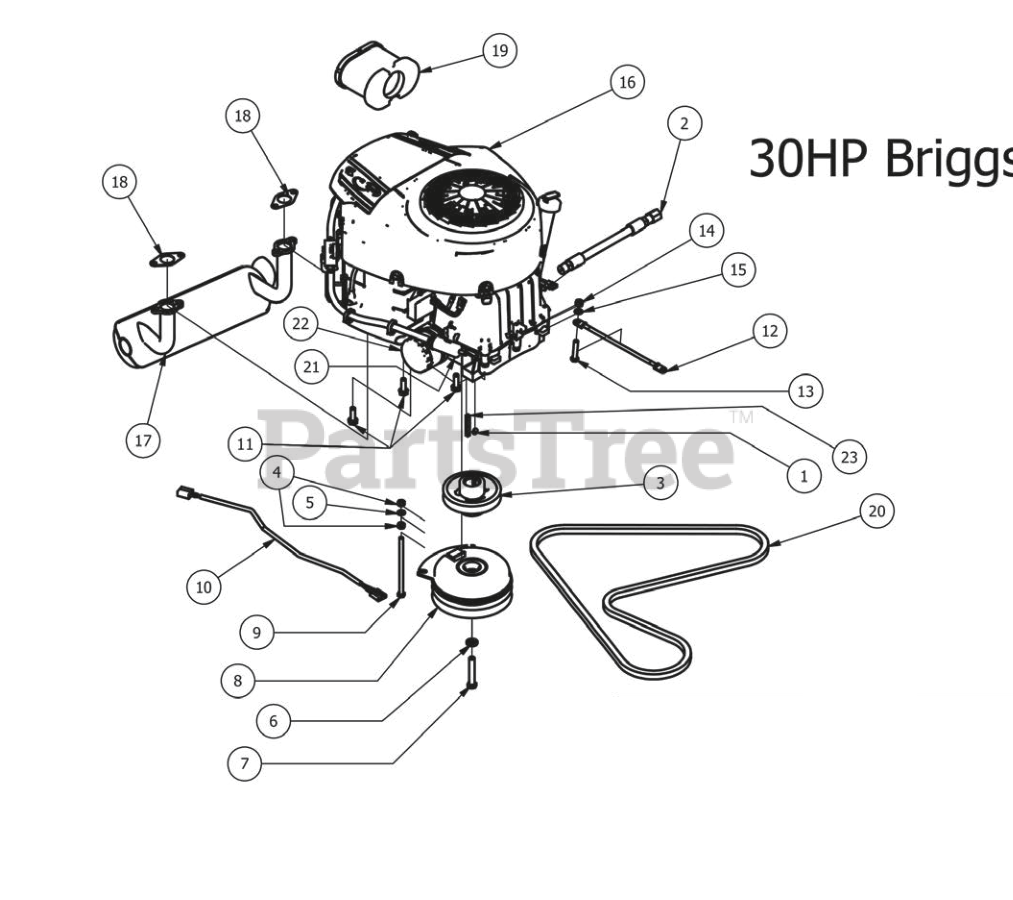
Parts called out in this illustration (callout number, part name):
1	5/16 Set Screw
2	Oil drain Hose
3	4 3/4 Motor Pulley
5	5/16" Lock Washer
6	7/16" Lock Washer
7	7/16" x 2 1/2" Hex Bolt
8	Clutch Assembly
9	5/16-18 x 5-1/2 GR 5 Hex Bolt
10	Clutch Pigtail
11	3/8 x 1 1/8 bolt
12	Starter to chassis cable
13	5/16" x 1 3/4" Hex Bolt
15	5/16" Lock Washer
16	30 hp Briggs Engine W/Cyclonic Filter
17	27 Hp Briggs Exhaust
18	Exhaust gasket
19	30hp Briggs Air Filter
21	Universal Inline Fuel Filter
22	Briggs Oil Filter
23	1/4 x 2 Square key Stock
